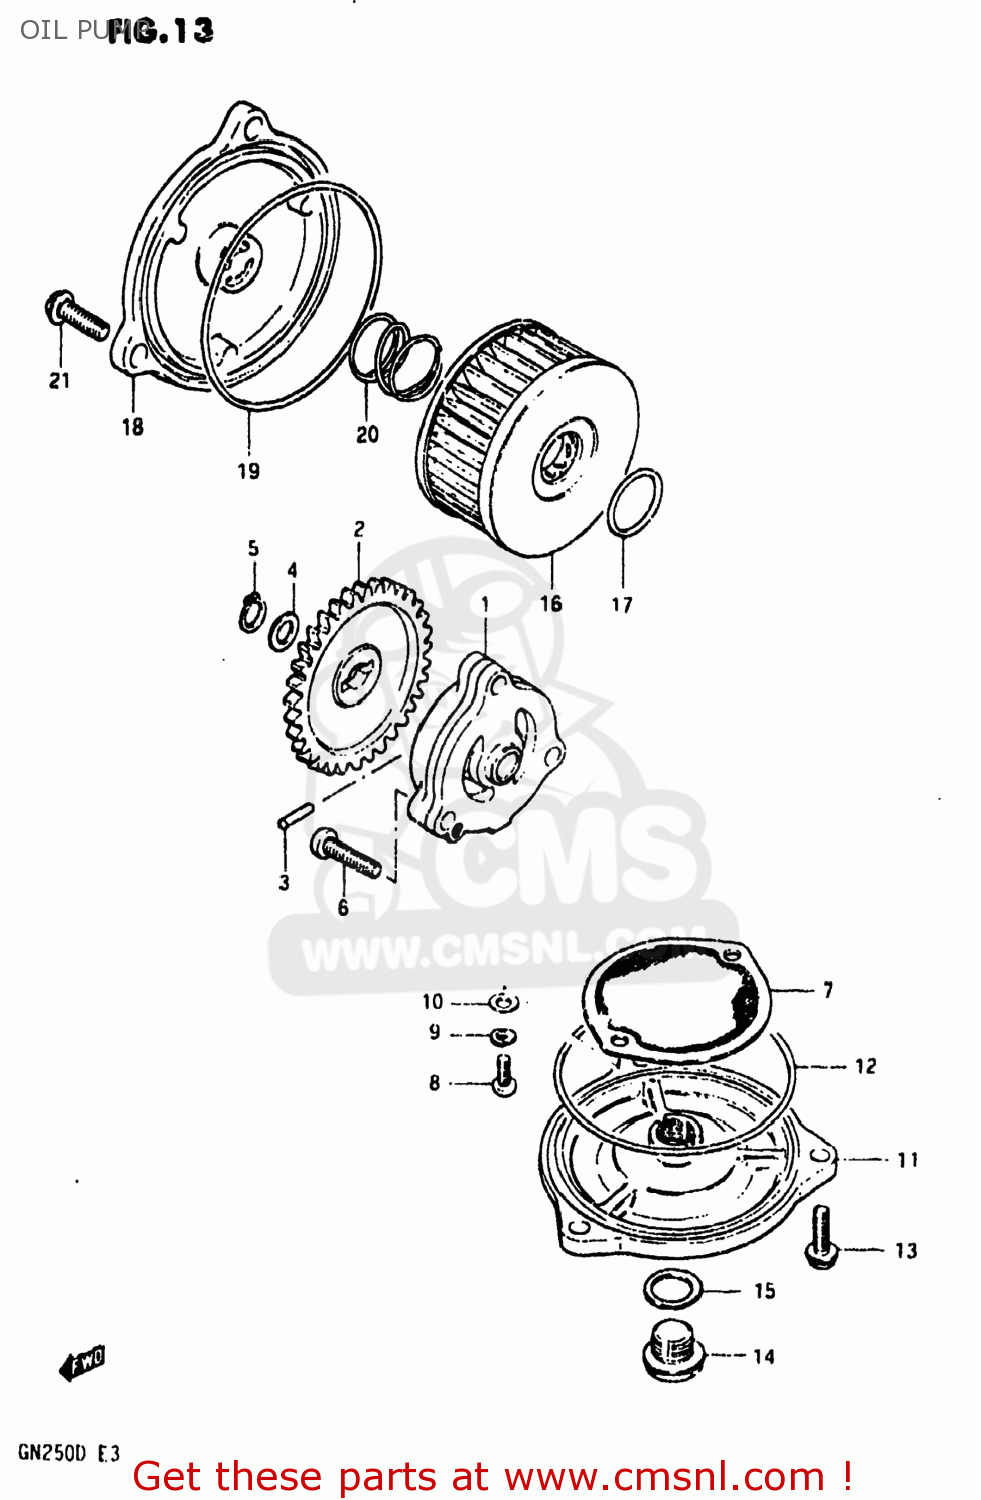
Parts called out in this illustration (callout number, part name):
1	PUMP ASSY,ENGINE OIL
2	GEAR,OIL PUMP DRIVEN(NT:33)
3	PIN(4X15.8)
4	SHIM
5	CIRCLIP
6	SCREW
7	STRAINER,ENGINE OIL
8	SCREW
9	LOCK WASHER
10	WASHER
11	CAP,OIL STRAINER
12	O RING(D:2.4,ID:85)
13	BOLT (6X20)
14	PLUG
15	GASKET(14X19.2X2) (NAS)
16	FILTER ASSY,ENGINE OIL
17	O RING(D:2.4,ID:15.8)
18	CAP,OIL FILTER
19	O RING(D:2.4,ID:73)
20	SPRING
21	BOLT (6X20)
